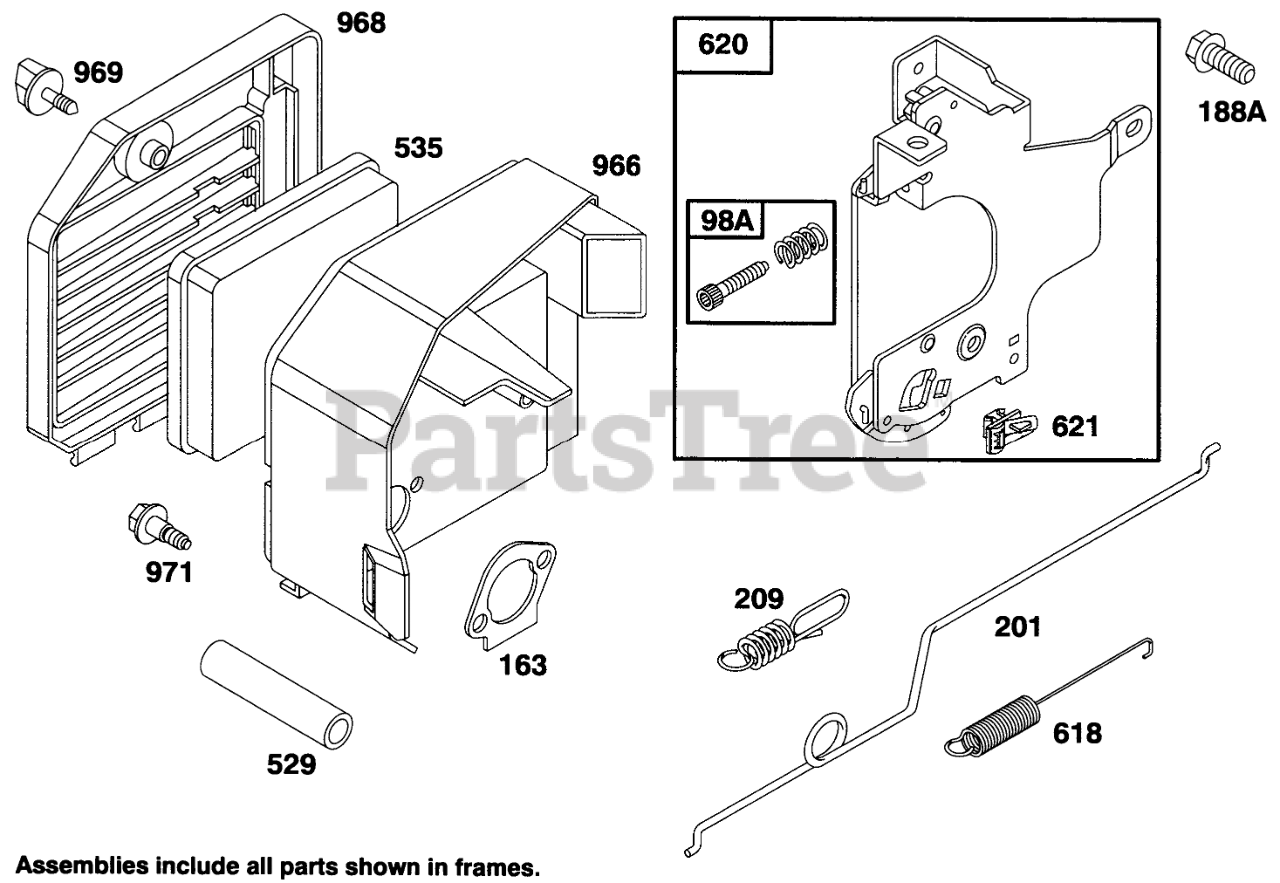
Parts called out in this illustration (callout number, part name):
98A	SPEED ADJUST. SCREW ASM
163	AIR CLEANER GASKET
188A	Screw-Cap
201	GOVERNOR LINK
209	GOVERNOR SPRING
529	BREATHER TUBE
535	FILTER ELEMENT
618	RETURN SPRING
620	CARBURETOR BRACKET
621	STOP SWITCH
966	AIR CLEANER BASE
968	AIR CLEANER COVER
969	AIR CLEANER SCREW
971	AIR CLEANER SCREW
